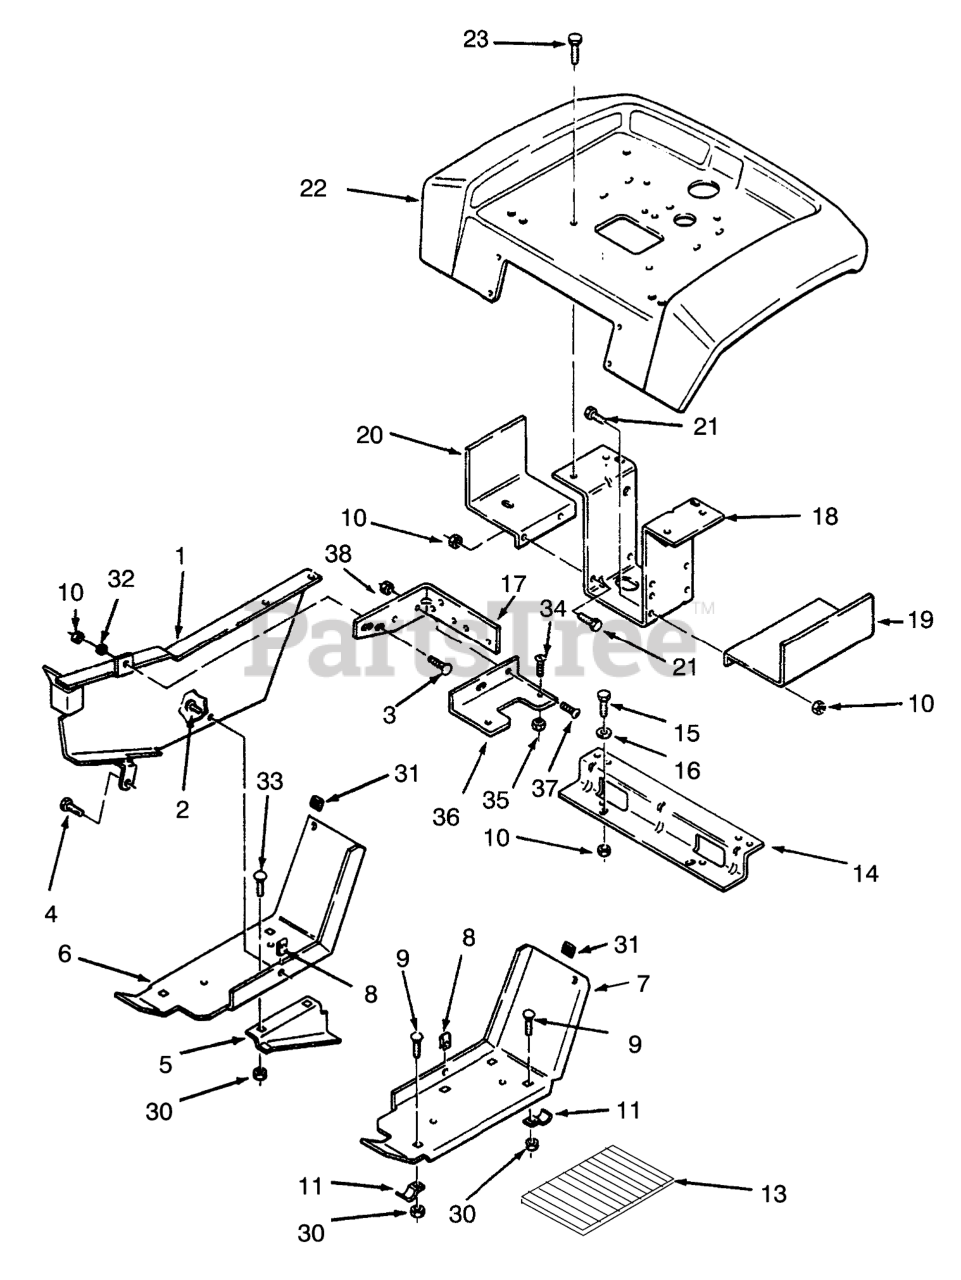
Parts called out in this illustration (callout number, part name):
1	Belt Guard
2	Screw
3	BOLT-CARR
4	Bolt
5	GUID-LOWER BLTR
6	Footrest-RH
7	FOOTREST LH R
9	BOLT-CARR
10	NUT-LOCK, NI
11	BRACKET
13	PAD-FOOTREST
14	BRACKET-FENDER B
15	SCREW-HH
16	WASHER-PLAIN
17	BRACKET-BELTB
18	Bracket-Fender
19	Fuel Tank Support LH
20	Support-FueITank RH
21	SCREW-HH
22	Fender
23	Bolt
30	NUT-LOCK, NI
31	BUMPER SJ5514 BLACK
32	NUT-PUSH
33	BOLT-CARR 5/16 SN
34	SCREW-PAN
35	Nut
36	FUSE HOLDERB
37	SCREW-HH
38	NUT-LOCK, NI
